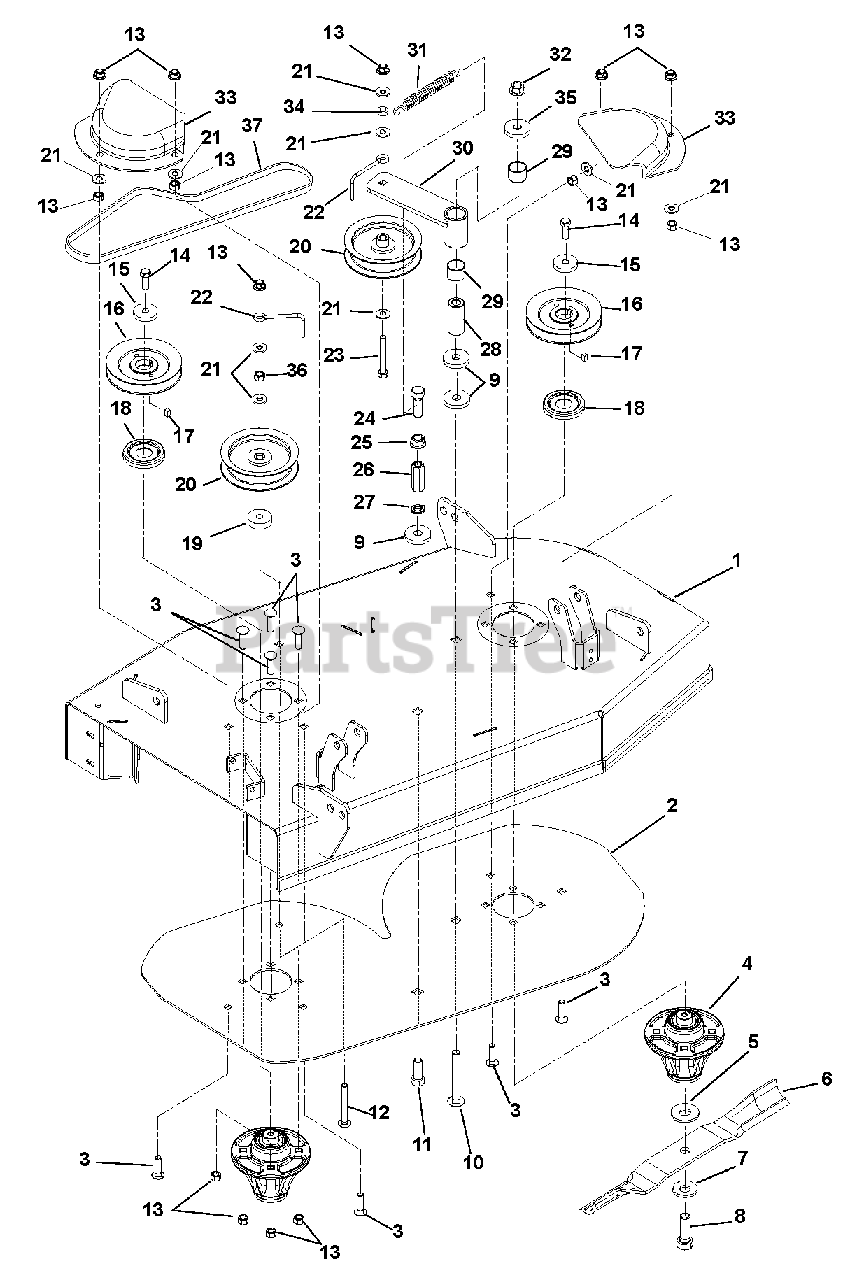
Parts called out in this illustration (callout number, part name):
1	Weldment 34" Fabricated Deck
2	Plate, 34" Doubler
3	Bolt, Round Head Square Neck .38-16 x 1.25
4	Spindle Assembly
5	Washer, Flat Steel .688 x 1.75 x .134
6	Blade, Mower
7	Washer, Beveled .63 x 1.625 x .140
8	Bolt, Hex .62-18 x 1.75 Grade 8
9	Washer, Flat Steel .515 x 1.625 x .25
10	Bolt, Round Head Square Neck .50-13 x 3.50 Grade 5
11	Bolt, Round Head Square Neck .50-13 x 1.25 Grade 5
12	Bolt, Round Head Square Neck .38-16 x 2.75 Grade 5 Full-Length Thread
13	Nut, .38-16 Nyloc Flange
14	Bolt, Hex .38-16 x 1.00 EP30 Grade 8
15	Washer, Flat Steel .406 x 1.50 x .245
16	Sheave, Spindle 4.75 Dia.
17	Key, Square .25 x .38
18	Dust Cap
19	Spacer, .39 x 1.50 x .380
20	Assembly, Idler 4"
21	Washer, Flat Steel .38 x .875 x .083
22	Belt Finger
23	Bolt, Hex .38-16 x 2.25 Grade 5
24	Bolt, Hex .50-13 x 1.50 Grade 5
25	Nut, Spin Lock Flange .50-13
26	Nut, Coupling .50-13 x 1.75
27	Washer, Lock 1/2
28	Bushing, Spacer .505/.500 x .999/.996 x 2.05/2.03
29	Bearing, 1.00 x 1.12 x .75
30	Idler, Arm
32	Nut, Locking Top Flange .50 - 13
33	Belt Cover
34	Bushing, Sleeve .377 x .624 x .235
35	Washer, Flat Steel .563 x 1.38 x .109
36	Nut, Locking Center .38-16
37	Belt, HA 97.00 Wrapped
